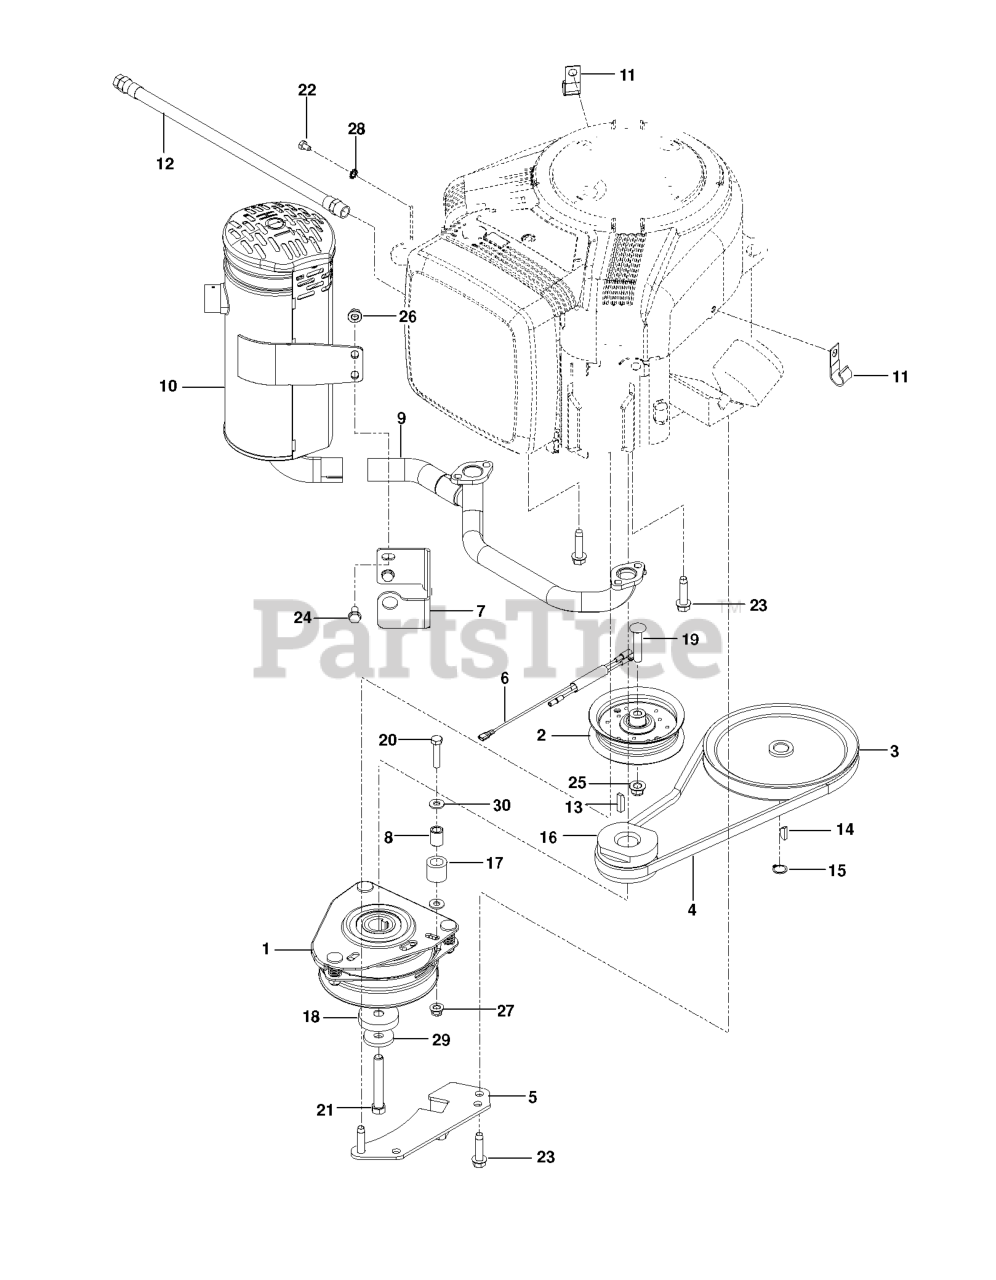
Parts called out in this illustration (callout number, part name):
1	CLUTCH CLUTCH ASSY, OGURA# GT1
2	PULLEY ASSY ASSY, IDLER 4"
3	PULLEY PLY-V 7.50 X .626
4	V-BELT V-BELT, HA-RAW EDGE LAM
5	CLUTCH CLUTCH STOP G2 HUSQ
6	HARNESS HARNESS, JUMPER B & S
7	BRACKET BRACKET, EXHAUST MOUNT
8	BUSH BUSH.,S.407 X .625 X .813
9	ELBOW ELBOW, EXHAUST
10	EXHAUST EXHAUST, B&S
11	CLIP P-CLIP, .500 INSULATED
12	HOSE HOSE, OIL DRAIN W/ CAP 18
13	KEY ¼ X ¼ 1 X 1
14	KEY KEY-WDRF .19 X .75 HRD#9
15	RING RG-RTNG-E X T .579 X .035
16	SHEAVE SHEAVE,ENGINE 1.002ID X
17	BUMPER BUMPER,RUBBER .62 X 1.0
18	SPACER SPACER, .450 X 2.00 X .
19	BOLT BOLT RDHDSQNK .38-16 X 2.
20	BOLT BOLT HEX .31-18 X 1.50 GR
21	BOLT BOLT HEX .44-20 X 3 GR8
23	SCREW SCREW .38-16 X 1½ TAP
24	SCREW SCREW, HEX-FL M8 X 1.25
26	LOCK NUT LOCKNUT,M8 X 1.25,FLA
28	WASHER WASHER LK EXT
29	WASHER WASHER, 7/16" SPRING DI
30	WASHER WASHER, FL-STL.312 X .7
